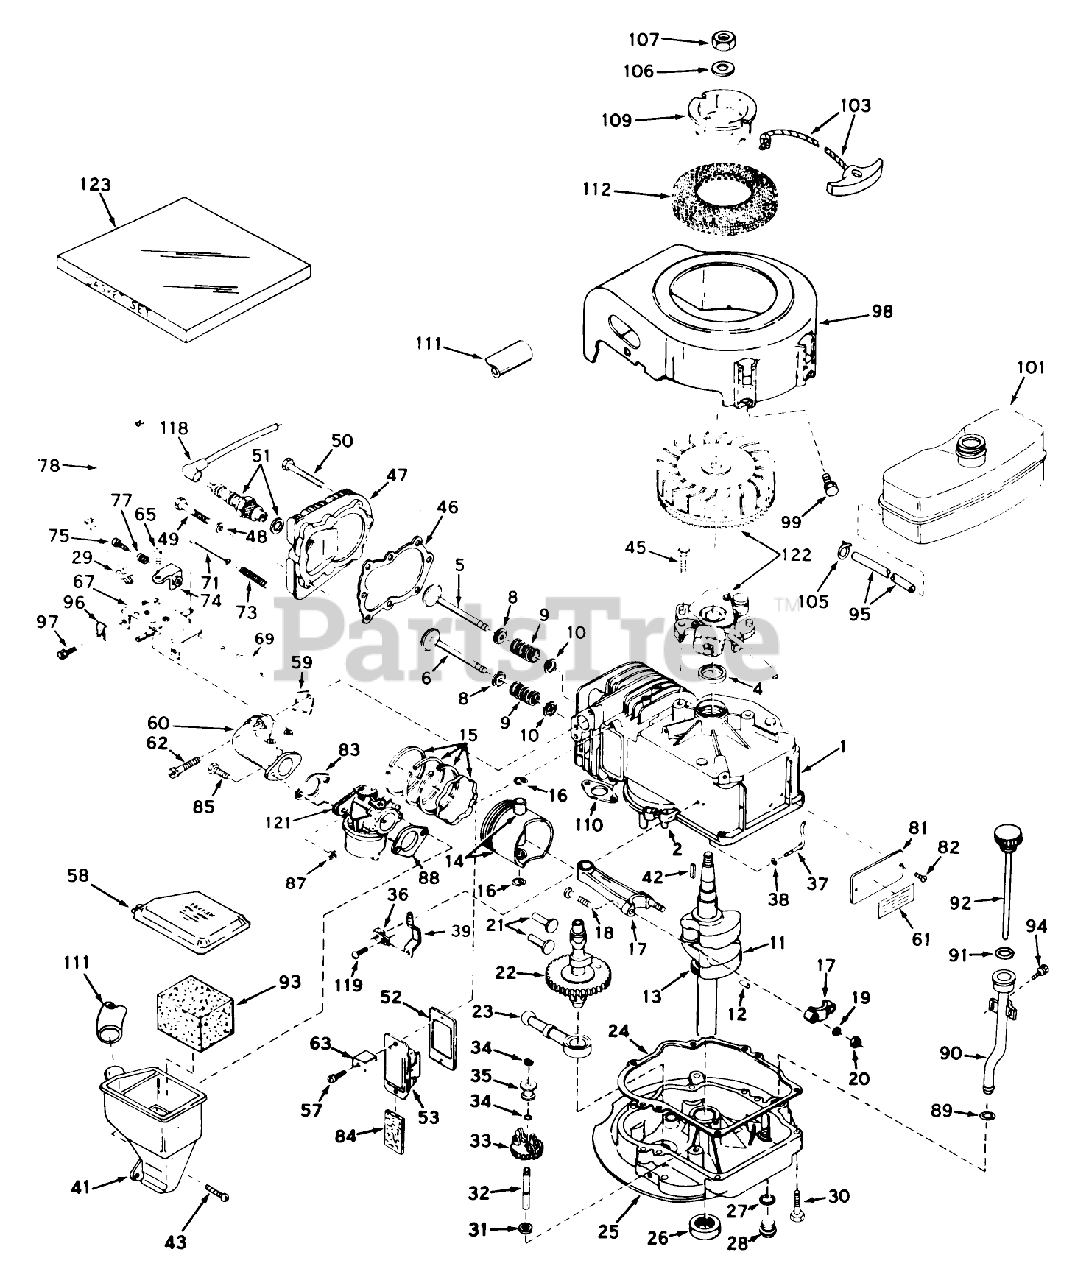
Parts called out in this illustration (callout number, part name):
1	Cylinder Assy. (Incl. Nos. 2, 4 103)
2	Pin-Dowel
4	OIL SEAL
5	Valve, Intake (Incl. Ref. #38, 39 40) (Std.)
5	Valve, Intake(1/32"overs.)(Incl. Ref. 8, 9 10)
6	Valve, Exhaust (Standard)(Incl. Ref. 8, 9 10)
6	Valve, Exhaust (1/32" Oversize)(Incl. Nos. 8, 9 10)
8	Cap-Upper Valve Spring
9	Spring-Valve
10	Cap-Valve, Spring
11	Crankshaft Assy. (Incl. Ref. 12 13)(Model LAV35-40455H)
12	Pin, Groove
13	Gear, Crankshaft
14	Piston Pin Assy. (Standard) (Incl. 2 of No. 16)
14	Piston Pin Assy. (.010 Oversize) (Incl. 2 of No. 16)
14	Piston Pin Assy. (.020 Over size)(Incl. 2 of No. 16)
15	Ring Set, Piston (Std.)
15	Ring Set, Piston (.010 o.s.)
15	Ring Set, Piston (.020 o.s.)
16	Ring-Retaining, Piston Pin
17	Rod Assy., Connecting (Incl. Ref. #17)
18	Bolt, Connecting
19	Washer
20	LOCKNUT
21	Lifter-Valve
22	Camshaft
23	Oil Pump ASM
24	Gasket, Mounting
25	Flange Assy., Mounting (Incl. Ref. 26, 27, 28 32)
26	Seal Oil
27	Gasket-Oil Drain
28	Plug Oil Drain
29	Terminal
30	Screw (1/4-20 x 1-1/4)
31	Washer-Flat
32	Shaft-Governor
33	Governor Gear ASM
34	Ring-Retaining
35	Spool-Governor
36	Clamp-Lever, Governor
37	Rod, Governor (Incl. No. 36)
38	Washer-Flat
39	Governor Lever
41	Body, Air Cleaner
42	Key Flywheel
43	Screw, Fil. Hd. Sems
45	Screw
46	Gasket-Cylinder Head
47	CYLINDER HEAD
48	Washer
49	Screw
50	Screw Hex Hd. Cap
51	SPARK PLUG
52	Gasket Breather
53	Breather Assembly (Incl. Nos. 52 84)
57	Screw
58	Cover, Air Cleaner
59	Gasket, Intake
60	Pipe, Intake
61	480B GIL SNWTHWR O/
62	Screw (1/4-20 x 1)
63	Retainer Clip
65	Screw (10-24 x 9/16)
67	Control Assy., Speed
69	Link Governor
71	Link-Governor
73	Spring, Governor
74	Brachet, Control
75	Screw, Hex Hd.
77	Spring
78	Wire, Ground
81	IDENTIFICATION PLATE
82	Stud
83	Gasket
84	Element-Breather
87	Nut and Lock Washer (1/4-28)
88	Gasket-Air Cleaner
89	O-Ring
90	Tube Assy., Oil Fill
91	O-Ring
92	Dipstick, Oil
93	Element, Air Cleaner
94	Screw (10-32 x 1/2)
95	Line-Fuel (8.62)
96	Conduit
97	Screw (10-32 x 3/8)
98	Housing, Blower
99	Screw (1/4-20x19/32)
101	Tank, Fuel
103	Rope Assy., Starter
105	Clamp-Line, Fuel
106	Washer
107	Hex Nut
109	Pulley Starter
110	Gasket Exhaust
111	Tube, Air Cleaner
112	Screen, Air
118	Cover-Spark Plug
119	Screw
121	Carburetor
122	Magneto
123	Gasket Set
